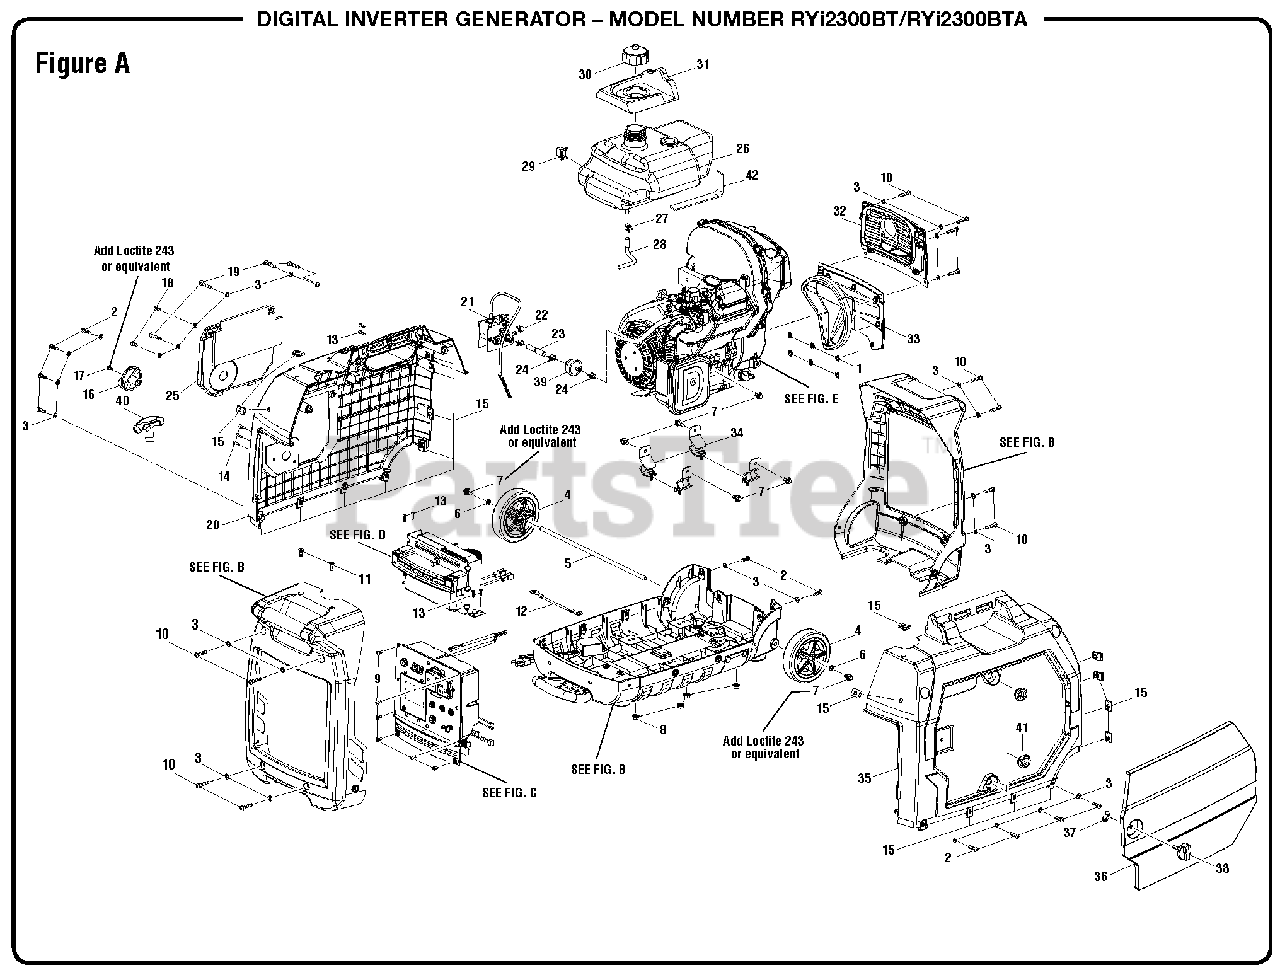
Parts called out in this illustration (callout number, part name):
1	Internal tooth washer (5 mm ID)
2	Screw (M5 x 20 mm, Button Soc. Hd.)
3	Washer (M5.3)
6	Lock Washer
7	Bolt (M6 x 12 mm, Hex Hd.)
8	Lock Nut (M6)
9	Screw w/Washer (M4 x 10 mm, T20 Torx Hd.)
10	Screw (M5 x 25 mm, Button Soc. Hd.)
11	Screw (M5 x 16 mm, Flat Hd.)
12	Ground Wire
13	Screw (M4 x 12 mm, T15 Torx Hd.)
14	Screw (M4 x 16 mm, Flat Hd.)
15	U-Clip (M5)
16	Control Knob
17	Screw (M4 x 10 mm)
18	Screw (M5 x 12 mm, Button Soc. Hd.)
19	Screw (M5 x 30 mm, T25 Torx Pan Hd.)
20	Left Housing Assembly
21	Engine Start/Stop Mechanism Assembly
22	Fuel Hose Clamp (3/8 in.)
23	Fuel Hose (4.5 mm and 6 mm)
24	Fuel Hose Clamp (9.5 mm)
25	Starter Cover Assembly
26	Fuel System Assembly
27	Clamp (10 mm)
28	Fuel Hose (6mm and 4.5 mm)
29	Fuel Tank Support
30	Vented Fuel Cap
31	Overspill Guard
32	Upper Exhaust Panel Assembly
33	Lower Exhaust Panel Assembly
34	Engine Isolator (45 Degree)
35	Right Housing Assembly
36	Maintenance Cover Assembly
37	E-Clip (5 mm Shaft)
38	Lock Knob
39	Fuel Filter
40	Recoil Handle
42	Rubber Pad
